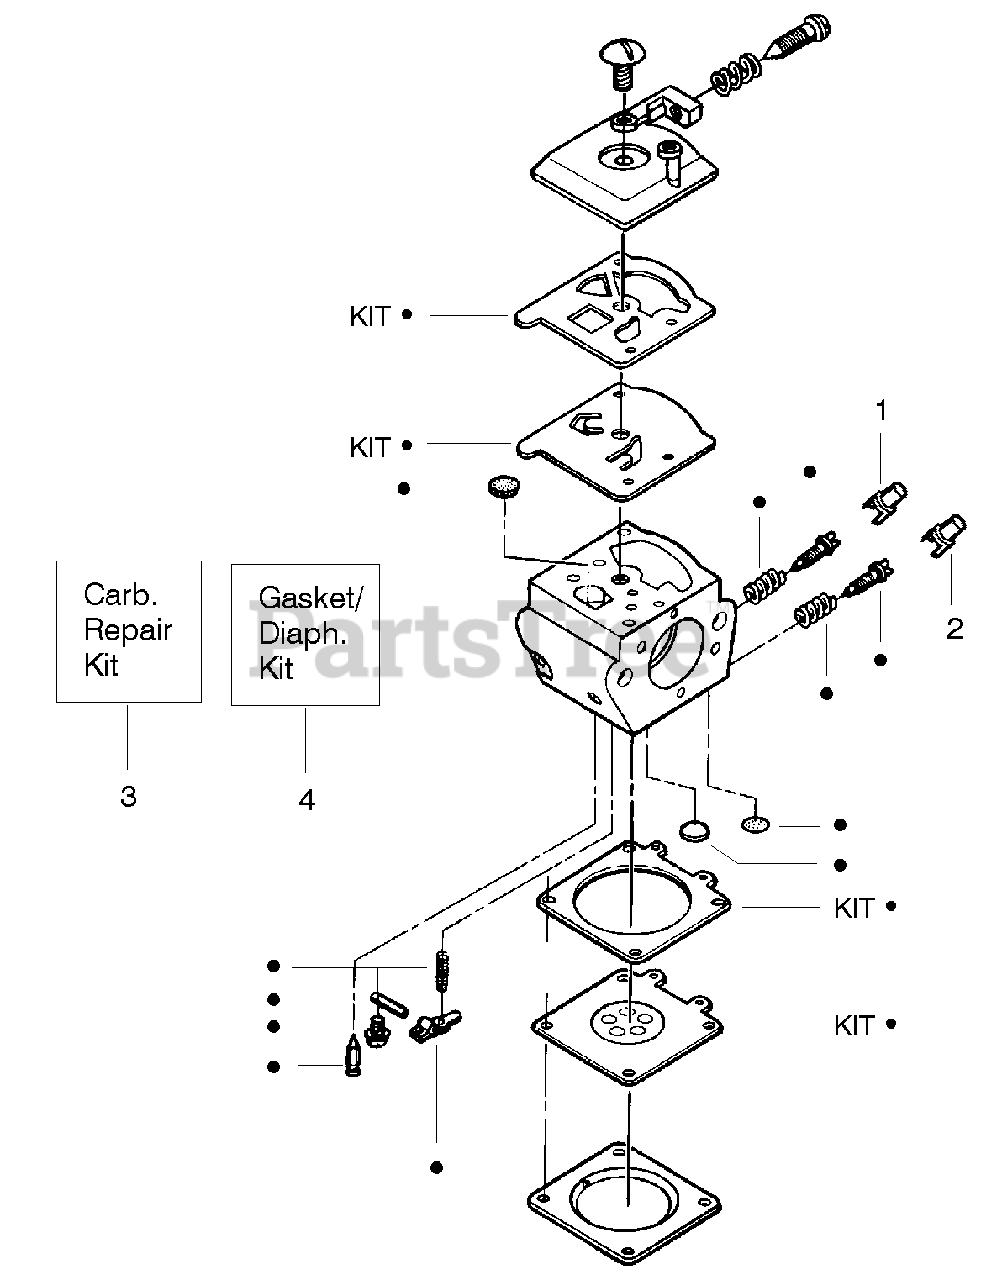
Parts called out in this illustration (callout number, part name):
1	Limiter Cap-High
2	Limiter Cap-Low
3	Carburetor Repair Kit (Indicates Contents)
4	Gasket/Diaphragm Kit (KIT=Indicates Contents)
